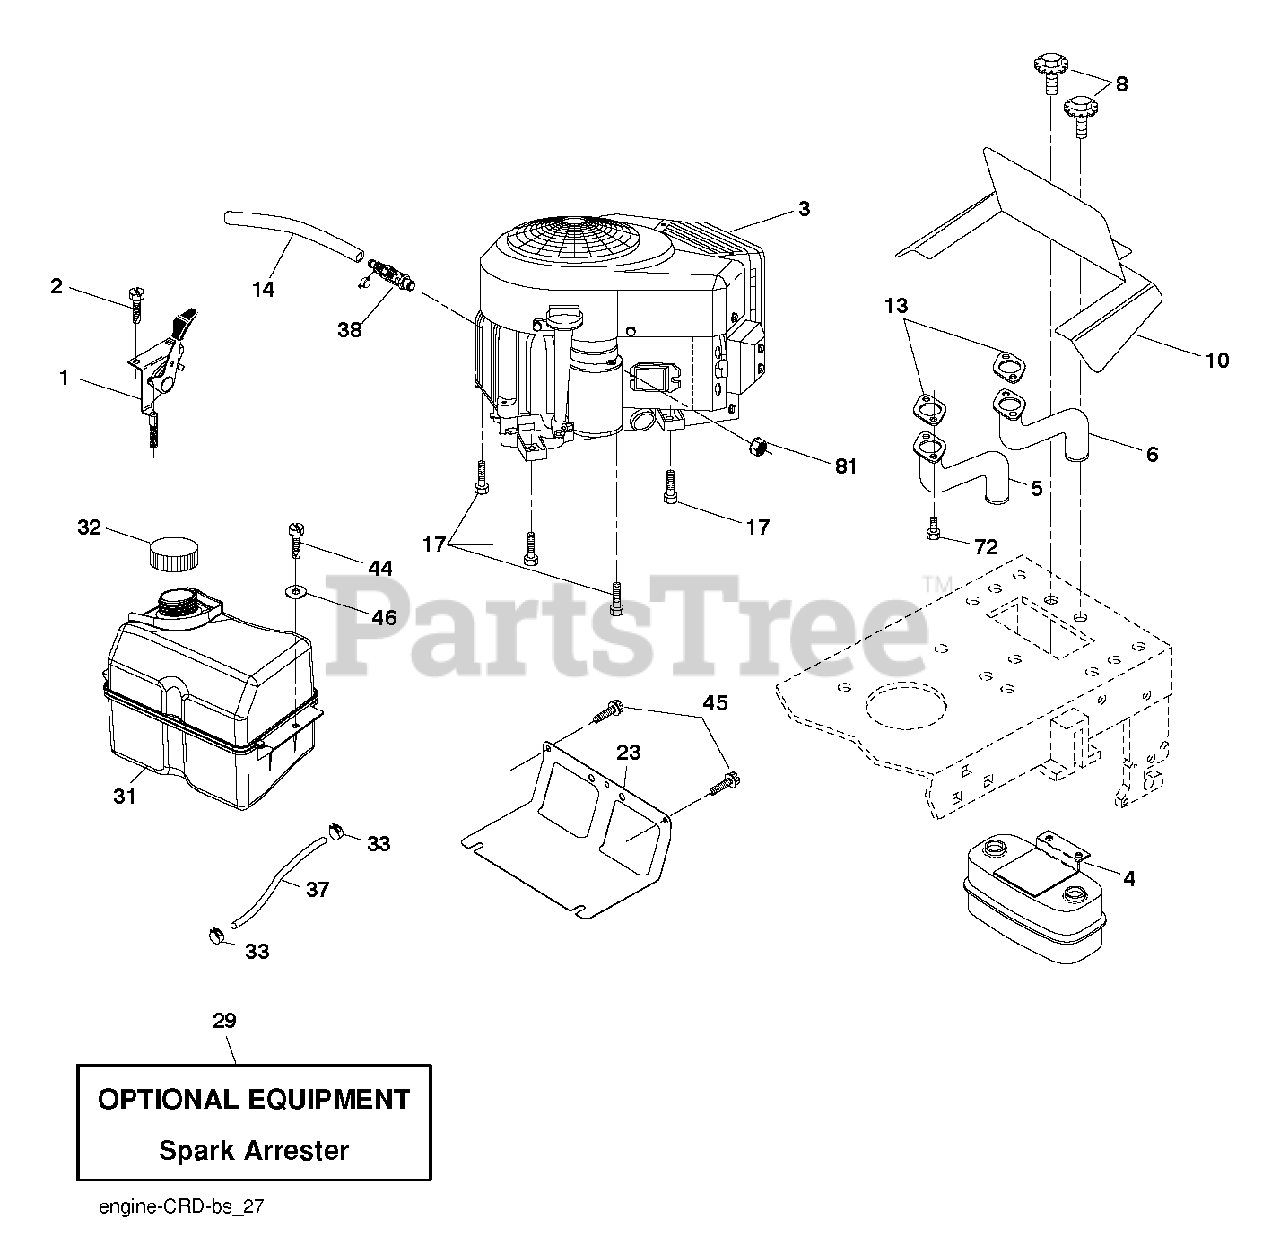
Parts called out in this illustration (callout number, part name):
2	SCREW
4	MUFFLER.TWIN.CYL.LOW.TONE
5	EXHAUST TUBE LH *SUBS/2*
6	EXHAUST TUBE RH
8	BOLT, 5/16-18 X 1 3/4
10	SHIELD.HEAT.MUFFLER
13	GASKET.MUFFLER
14	TUBE, DRAIN OIL ASM.
23	SHEILD.BROWNING.DBR.GUARD
29	ARRESTER SPARK (OPTIONAL)
32	CAP ASM.FUEL.2.25"FR.
38	VALUE.OIL.DRAIN
44	SCREW HEXWSHR 1/4-20X3/4
45	SCREW, 3/8-16X3/4
72	SCREW.SOCKET.HEAD.5/16-18
81	NUT
